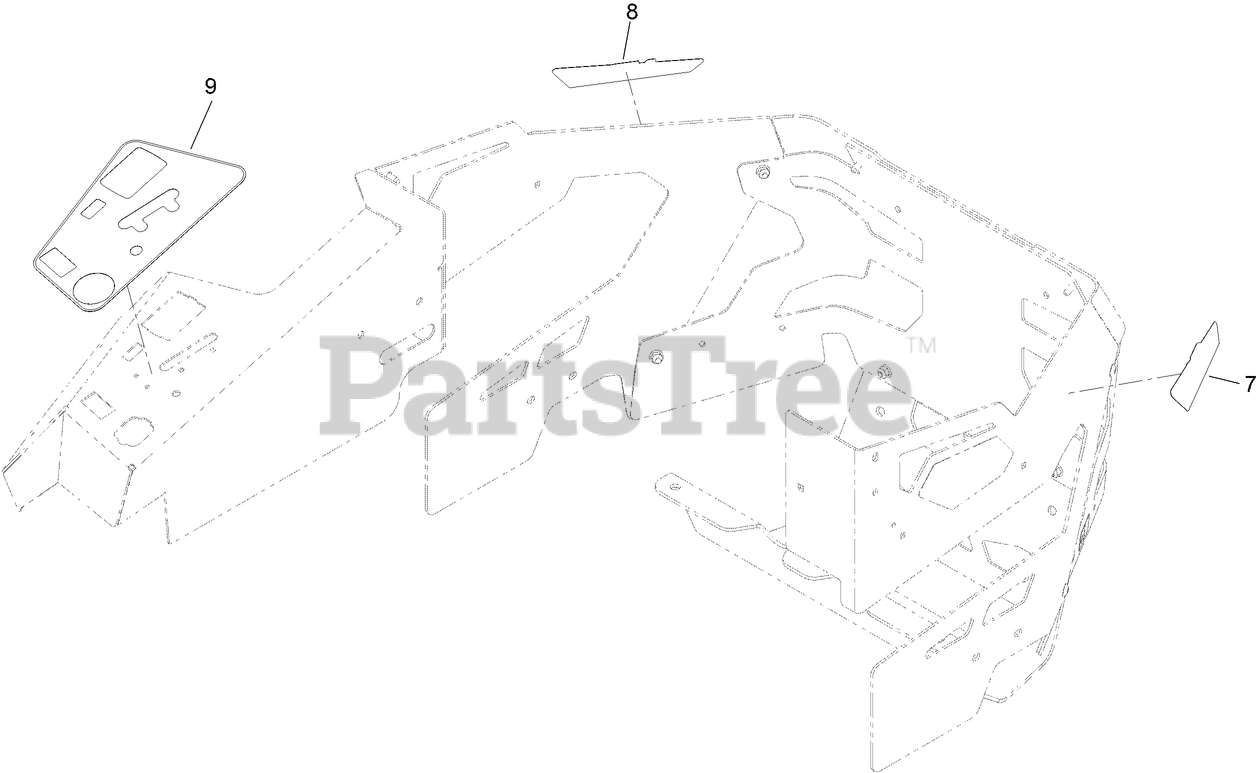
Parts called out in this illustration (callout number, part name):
7	DECAL - HDX PRO
8	DECAL - HDX PRO
9	DECAL-PANEL, CONTROL
